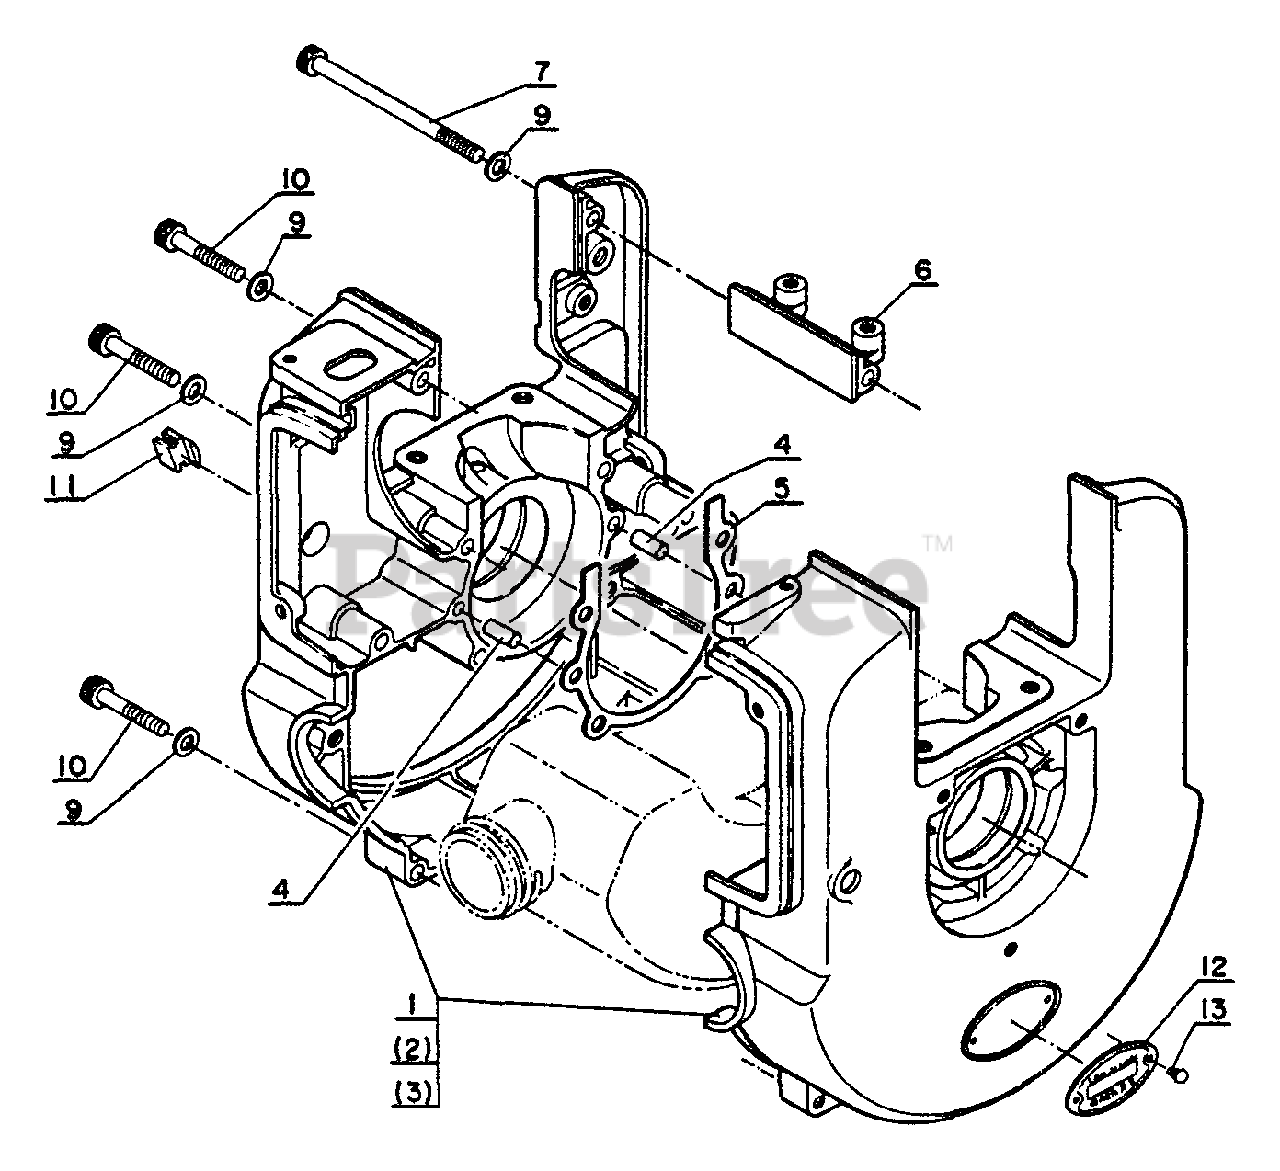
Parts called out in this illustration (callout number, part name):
1	CRANKCASE KIT
4	PIN, LOCATING 4
5	GASKET, CRANKCASE
6	BRACKET, MUFFLER
7	SCREW - 4×65
9	WASHER 4 MM
10	SCREW - 4×20
11	PLUG
12	MODEL PLATE
13	RIVET
